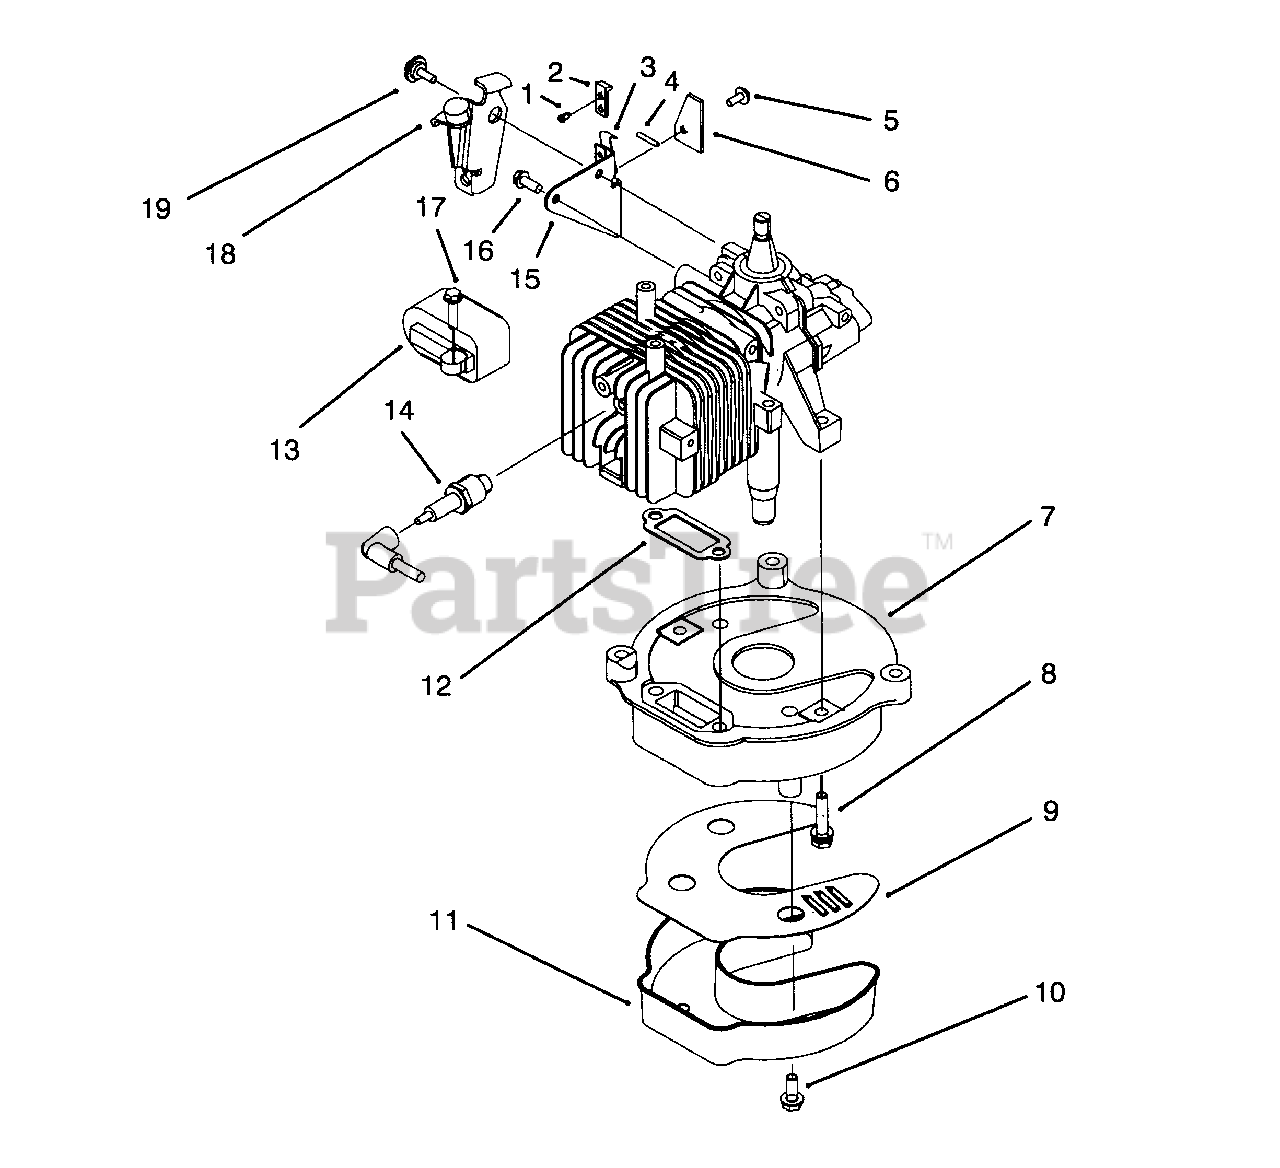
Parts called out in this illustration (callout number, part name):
1	Rivet-Self Expanding
2	Strap-Insulation
3	Strap-Ground
4	Wire-Brake Switch Lead
5	Screw-Thread Forming
6	Stop-Ground Strap
7	Plate-Muffler
9	Baffle
11	Cover-Muffler
12	Gasket-Exhaust
13	CD Ignition Assembly
14	Plug-Spark
15	Plate-Brake Mount
16	Screw
17	Screw-Hex Washer Hd.
18	Plate-Brake
19	Screw-Shoulder
